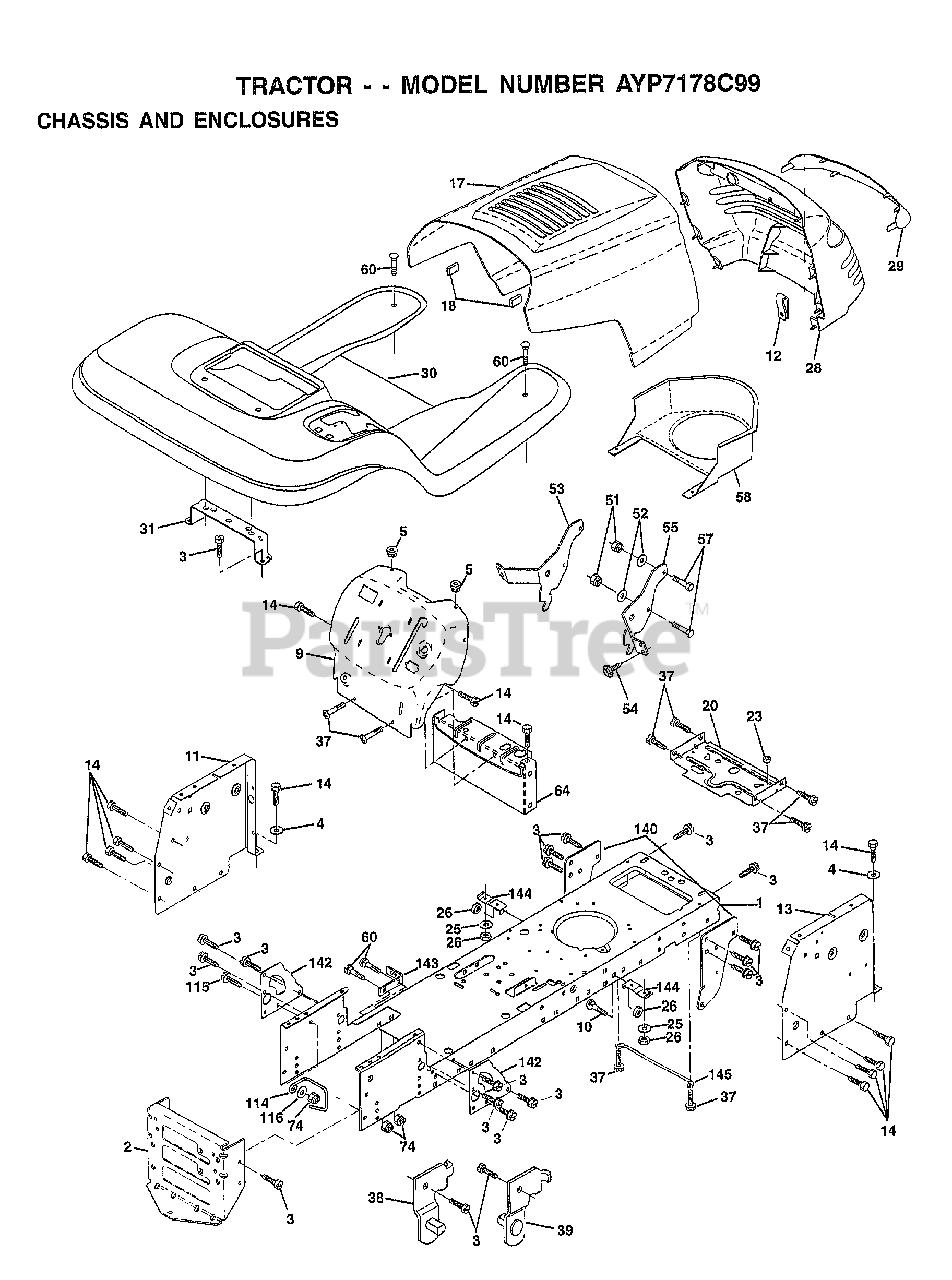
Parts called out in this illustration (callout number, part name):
1	CHASSIS.STLT.STAMPING
3	SCREW
4	WASHER
5	BUMPER-HOOD/DASH
11	"PANEL-DASH,LH"
12	CLIP.TINNERMAN
13	PANEL.ASM.DASH.RH
14	SCREW LT
17	HOOD.STEEL.ASSY
20	"PLATE-MTG,BATT/FU"
25	WASHER
26	NUT
28	GRILL
29	GRILLE.LENS
30	FEND/FTREST PNT
31	BRACKET SUPT FEND
37	SCREW LT
38	BRACKET ASM LH
39	BRACKET ASM RH
51	NUT
52	WASHER
53	BRACKET.GRILLE.LH
54	SCREW.HEX.WS.HD
55	BRACKET.GRILLE.RH
58	AIR DUCT
60	BOLT
64	DASH-LOWER
114	"KEEPER-BELT,RR.LH"
115	SCREW
116	WASHER
140	BRKT SUSPENSION
142	PLATE.REINFORCEMENT
143	"BRKT-S'BAR,CHASSI"
144	BRKT-FOOTREST
145	"ROD POVOT,CHASSIS"
